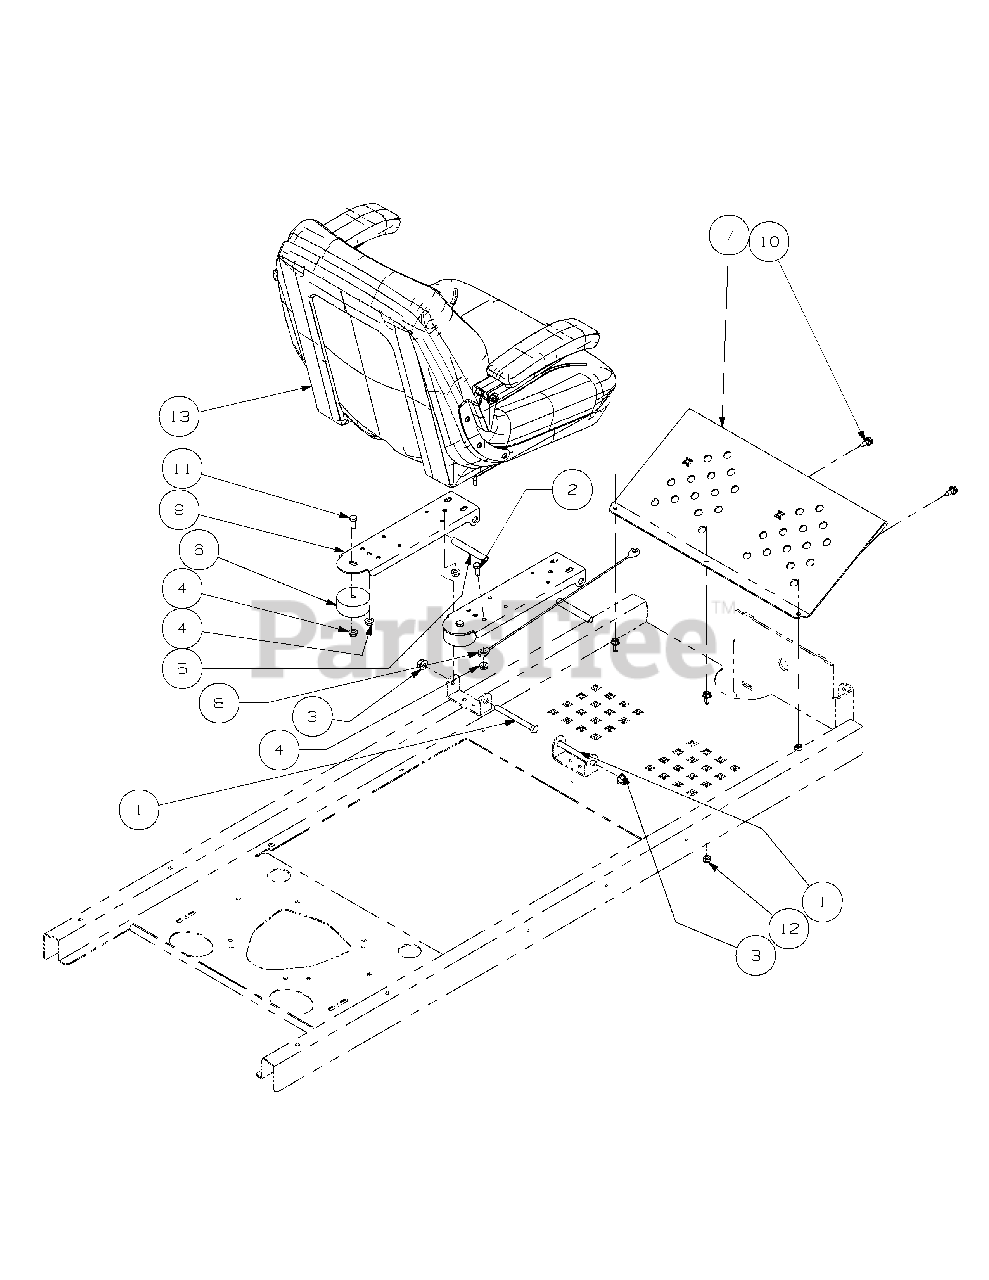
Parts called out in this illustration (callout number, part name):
1	Hex Cap Screw, 3/8-16, 4.00
2	Hex Cap Screw, 5/16-18 x 3/4
3	Flange Lock Hex Nut, 3/8-16
4	Nut, 5/16-18, Hex Flange Lock
5	Spacer, .370 ID x .500 OD x 3.45
6	Bumper, 2.50 OD x 1.13 Long
10	Self Tapping Screw 5/16-18 x .750
11	Hex Cap Screw, 5/16-18 x .75
12	Nylock Nut, 5/16-18
13	Seat
